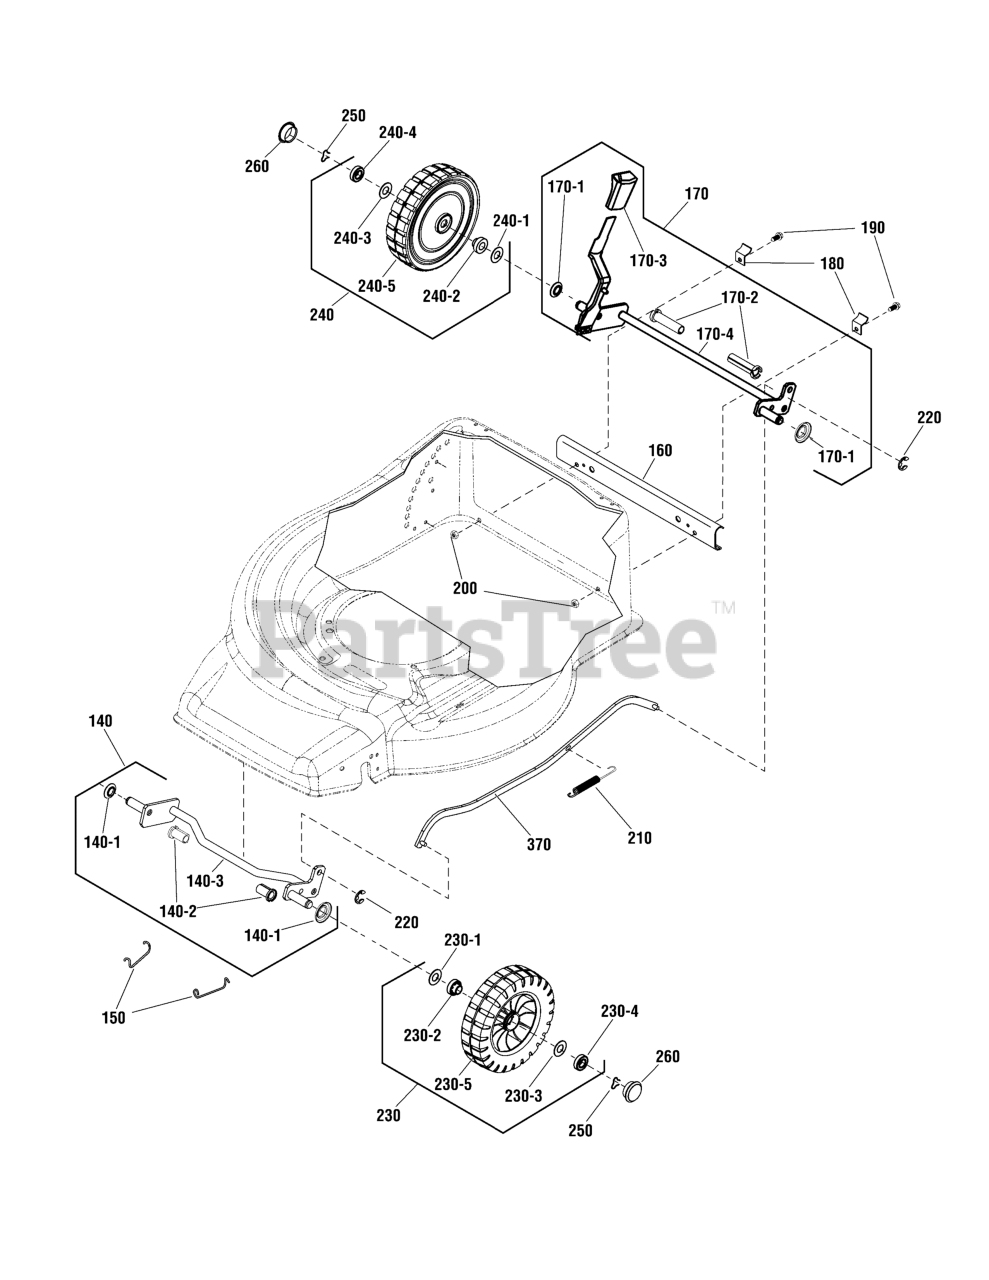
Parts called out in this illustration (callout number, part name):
140	AXLE ASSEMBLY, Front
140-1	DUST SEAL
140-2	BUSH, Front Axle
140-3	AXLE, Front
150	CLIP, Axle, Front
160	REAR SKIRT, Safety
170	AXLE ASSEMBLY, Rear
170-1	DUST SEAL
170-2	BUSH, Rear Axle
170-3	KNOB, Height Adjust
170-4	AXLE, Rear
180	CLIP, Axle, Rear
190	SCREW, Hex Head, M6x16
200	NUT, Nylock, M6
220	CIRCLIP
230	WHEEL, 6in Easytrak 150, Front
230-1	WASHER, Wheel, Front
230-2	BUSHING, Wheel, Front
230-3	WASHER, Wheel, Front
230-4	BEARING, Wheel, Front
230-5	TYRE & HUB, Front
240	WHEEL, 7in Easytrak 175, Rear
240-1	WASHER, Wheel, Rear
240-2	BUSHING, Wheel, Rear
240-3	WASHER, Wheel, Rear
240-4	BEARING, Wheel, Rear
240-5	TYRE & HUB, Rear
250	CAPTIVATED CLIP, Wheel
370	LINK, Connecting
600	RIVET
